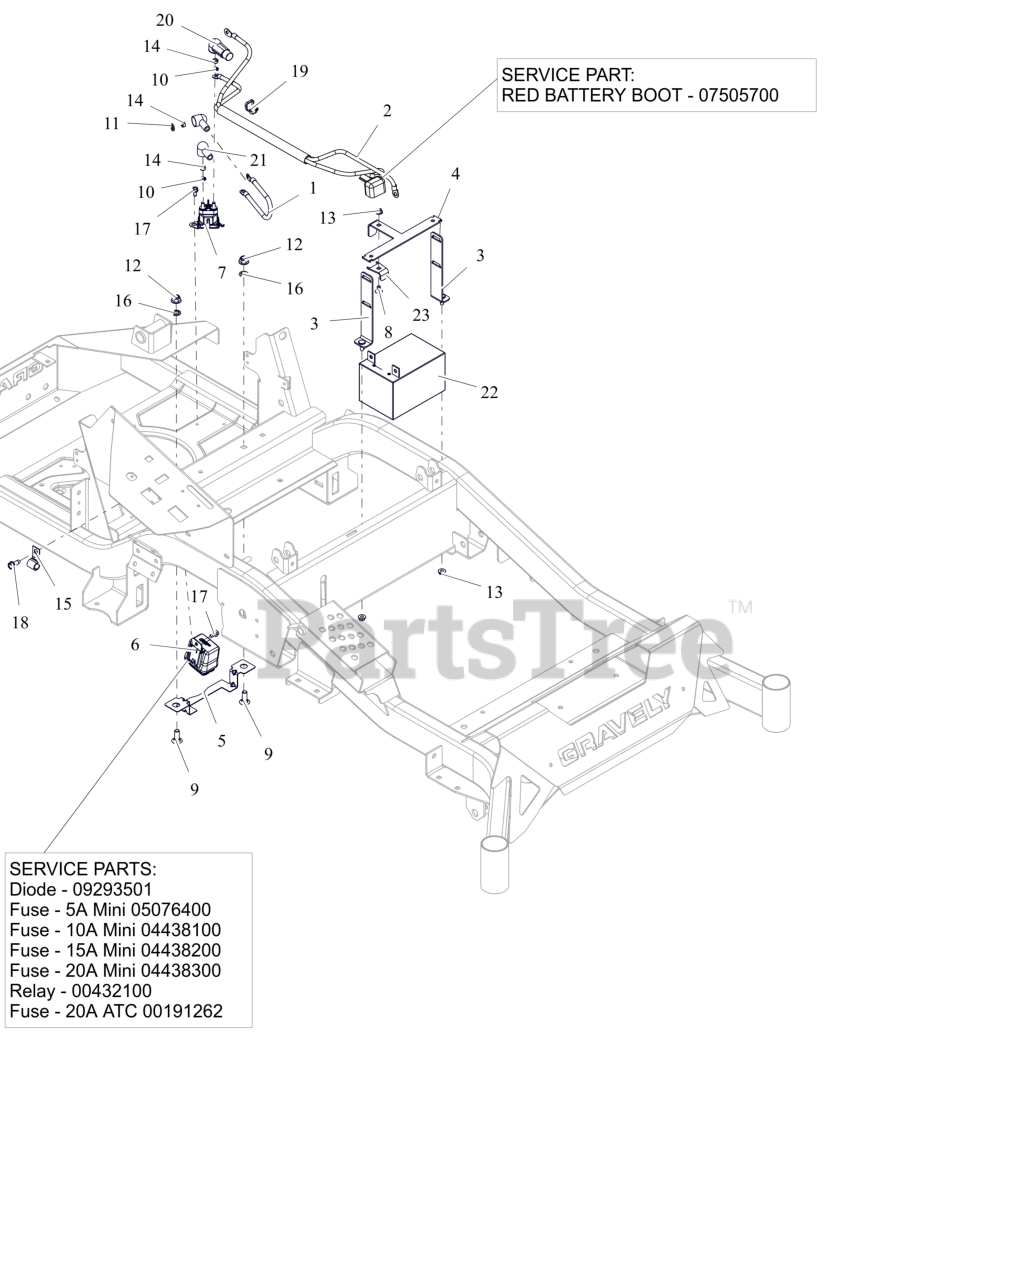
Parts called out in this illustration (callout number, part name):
1	CABLE, POS W/(2)1/4 RING 9.0LG
2	HARNESS, BATTERY HD
2	INSULATOR
3	WMT,BATTERY MOUNT HOLD DOWN
4	BRKT, BATTERY TIE DOWN
5	GUARD, ELECTRICAL HARNESS
6	HARNESS, WIRE
6	DIODE, CONNECTOR SHELL
6	FUSE, 5 AMP MINI-ATC
6	FUSE,10 AMP MINI-ATC
6	FUSE,15 AMP MINI-ATC
6	FUSE,20 AMP MINI ATC
6	FUSE, 20 AMP BLADE S/O
7	RELAY,MICRO5 TERML W/RESISTOR
7	SOLENOID, STARTER (SEALED)
8	BLT, RHSN .25-20X.500 G5 ZCC
9	BLT, RHSN .38-16X1.00 G5 ZCC
10	WSHR,LK-EXT.262X.502X.026 ZCC
11	WSHR,LK-REG .312X.078 ZCC
12	NUT,NYL-FLG .38-16 GF ZCC
13	NUT-LK-TOP-FLG .250-20 GF ZCC
14	NUT-STD M6-1.0 ZCC
16	NUT-PUSH .38 DIA. PAL ZINC
17	SCR-TAP .25-20X.50 HWH ZCC
18	SCR,TAP .312-18X.75 HWH TR ZCC
19	CABLE TIE W/ TREE (.25 HOLE)
20	BOOT, .65ID POS
21	BOOT, EYELET TERMINAL
22	BATTERY, 12V 12A -190CCA
23	BRKT, BATTERY HOLD
